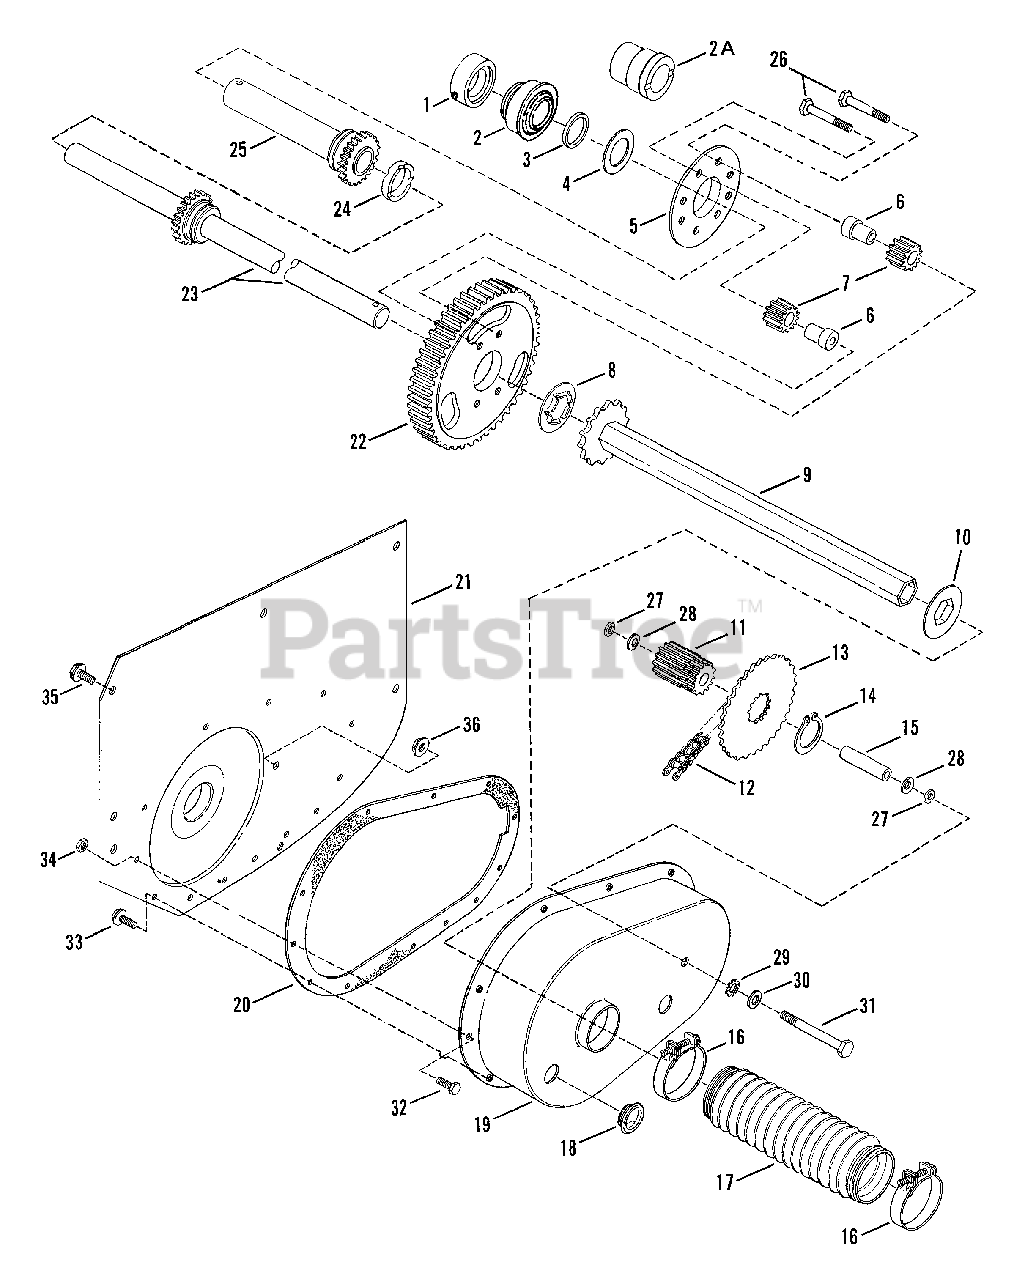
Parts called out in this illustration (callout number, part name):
1	COLLAR, Lock (12 & 14 HP Models)
2	BALL BEARING, Axle, R.H. Fender (12 & 14 HP Models)
2A	BEARING, Axle, R.H. Fender (6.5 & 8 HP Models)
3	SPACER, Short Axle
4	WASHER, Thrust
5	PLATE, Differential
6	SPACER, Pinion
7	PINION GEARS, Differential 94)
8	WASHER, Thrust
9	ASSEMBLY, Drive Hex Tube
10	WASHER, Hex Insert
11	GEAR, 11 Teeth, 10 Pitch
12	CHAIN, 46 Pitch (#35)
13	SPROCKET
14	RING, Retaining External
15	SPACER
16	CLAMP, Boot
17	BOOT, Oil Seal
18	PLUG, Oil Fill & Check
19	CASE, Transmission
20	GASKET, Transmission Case
21	FENDER, Right Hand (Ball Bearing)(2.498" Hole)
22	GEAR, 63 Teeth, 10 Pitch
23	AXLE, Long
24	SPACER, Differential (1.25" ID x .425 Wide)
25	AXLE, Short
26	CAPSCREW, 5/16-24 x 1-5/8" Hex, Special Lock
27	O-RING, 5/16"
28	WASHER, 5/16" Belleville
29	WASHER, 5/16" External Tooth
30	WASHER, 5/16" Flat
31	BOLT, 5/16-24 x 2-5/8" Idler
32	SCREW, 1/4-20 x 5/8" Hex head Cap
33	SCREW, 1/4-20 x 5/8" Self-Tapping
34	NUT, 1/4-20 Hex Center Lock, Grade B or 5
35	SCREW, 5/16-18 x 5/8", Self-Tapping
36	NUT, 5/16-24 Hex Flange Lock
